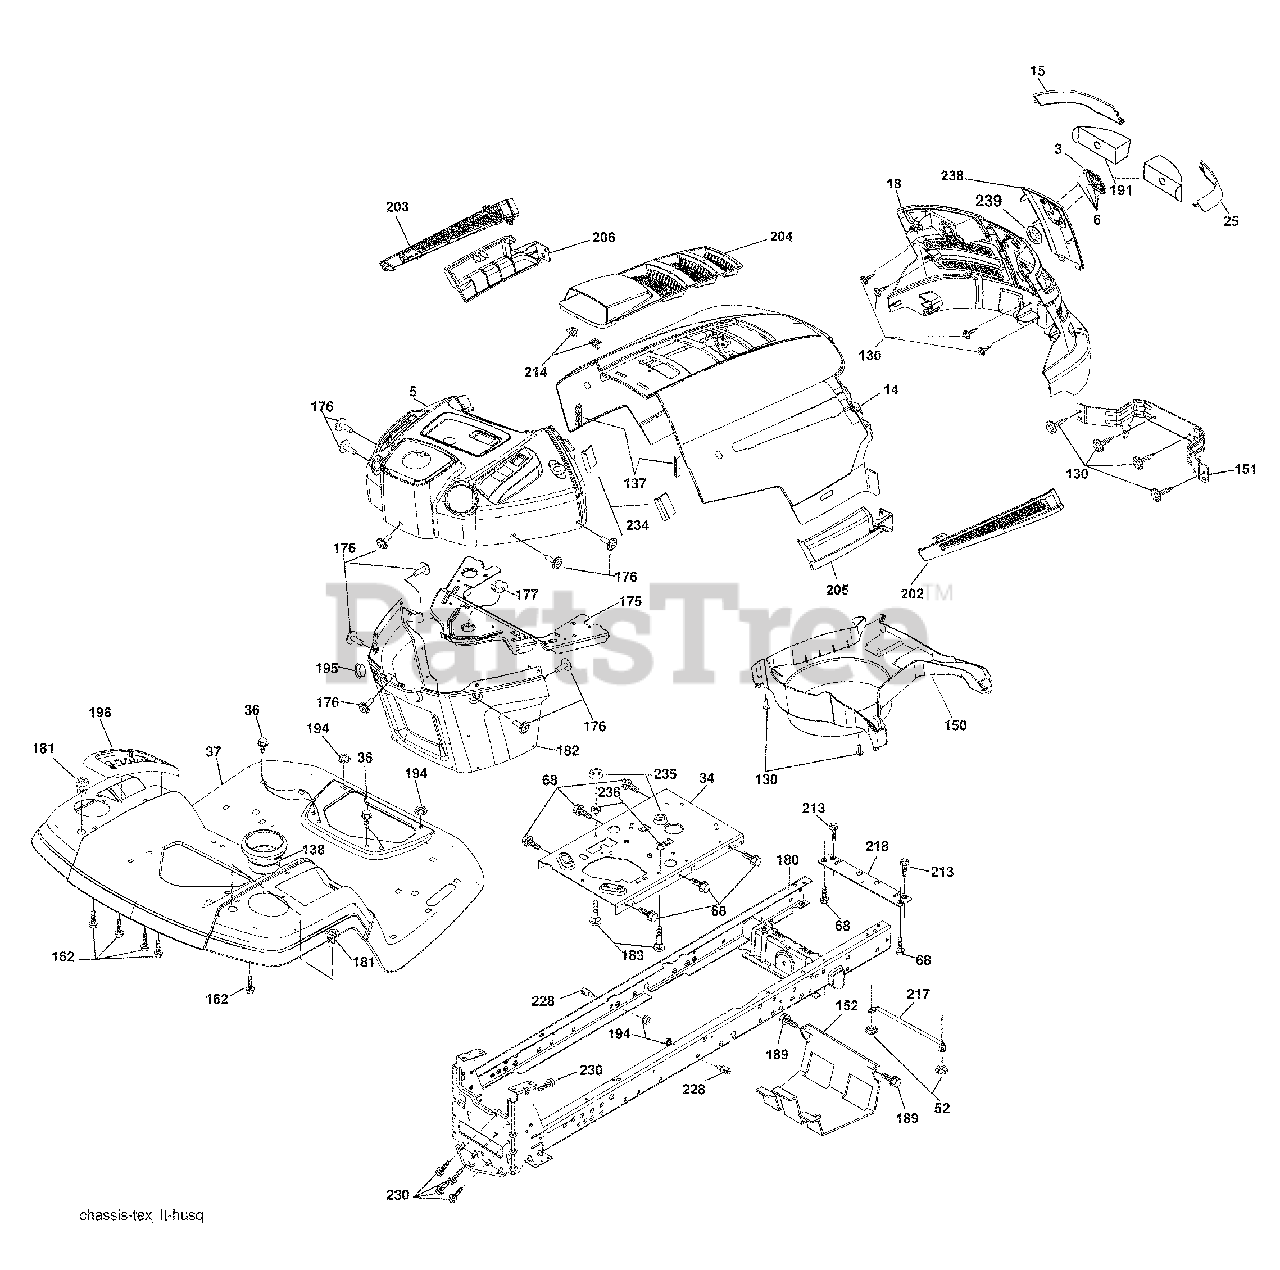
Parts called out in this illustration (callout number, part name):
3	Logo
5	Dash
14	Hood
15	Lens LH
18	Grille/Lens Asm.
25	Lens RH
34	Plate Engine
36	Screw 5/16-18 x 3/4
37	Fender
52	Nut Crown Lock 5/16
68	Screw THDROL 5/16-18 x 1/2
130	Screw 10 x 3/4 Single Lead-Hex
137	Bumper Dash
138	Cupholder
151	Bracket Pivot
152	Shield Browning
175	Crossmember
176	Screw 10-24 x 5/8
177	Bushing Steering
180	Chassis
181	Bushing Mtg. Fender Crgo
182	Dash Lower
183	Bolt 5/16-18 unc x 1-1/4
189	Screw 5/16-18 x 3/4
191	Insert Reflective
194	Nut Lock Hex Flange 5/16-18
195	Plug Dash
196	Console Asm. Deck Lift
202	Vent Side Hood RH
203	Vent Side Hood LH
204	Vent Top Hood
205	Skirt Side RH
206	Skirt Side LH
213	Bolt 5/16-18 x 3/4
214	Clip Retainer
217	Rod Pivot Hood
218	X-Piece Hood Stop
228	Stud Fastener
230	Bolt Shoulder 5/16-18
234	Bumper Hood
235	Spacer Fender
236	Nut Lock 5/16-18 unc
238	Trim
239	Clip Tinnerman
